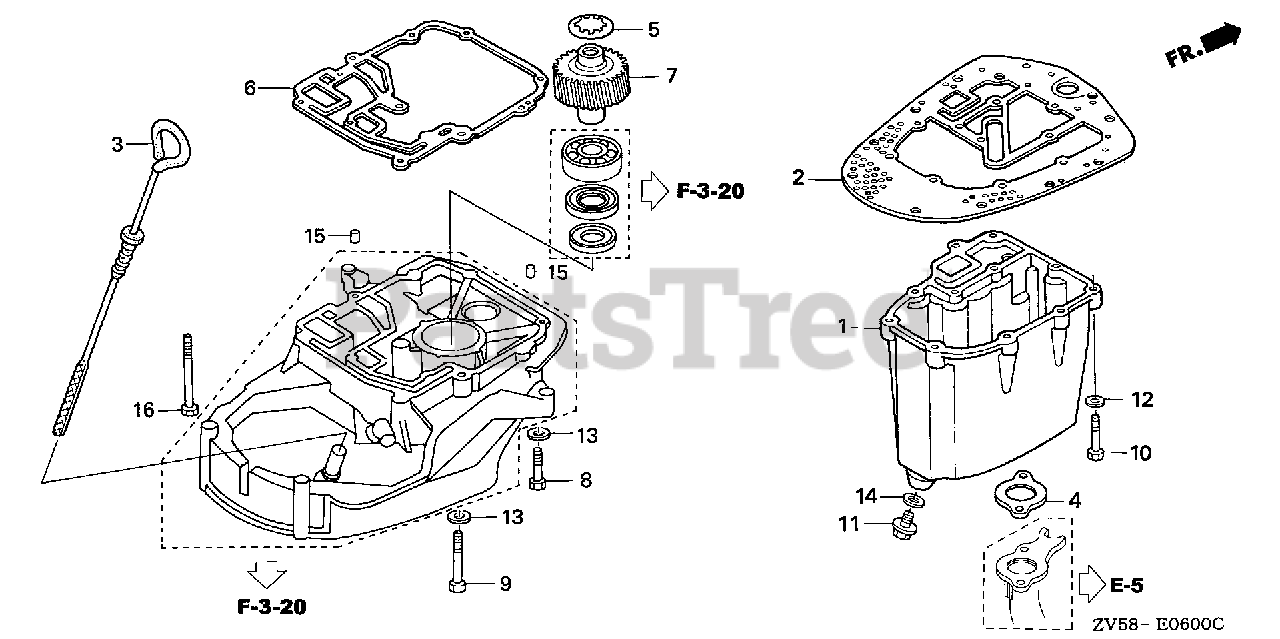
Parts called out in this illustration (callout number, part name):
1	PAN, OIL *TGRAY* (GRAY)
2	GASKET, OIL PAN
3	DIPSTICK, OIL
4	GASKET, EX. PIPE
5	SPRING, THRUST
6	GASKET, PRIMARY GEAR CASE
7	GEAR, PRIMARY DRIVEN (33T)
8	BOLT, HEX. (8X35) Use up to Frame SN 4800712.
9	BOLT, HEX. (8X55)
10	BOLT, HEX. (6X25) Use up to Frame SN 4800342.
11	BOLT, DRAIN PLUG
12	WASHER, PLAIN (6MM) Use up to Frame SN 4800342.
13	WASHER, PLAIN (8MM) Use up to Frame SN 4800712.
14	WASHER, DRAIN PLUG (12MM)
15	PIN, DOWEL (6X10)
16	BOLT, FLANGE (8X75)
